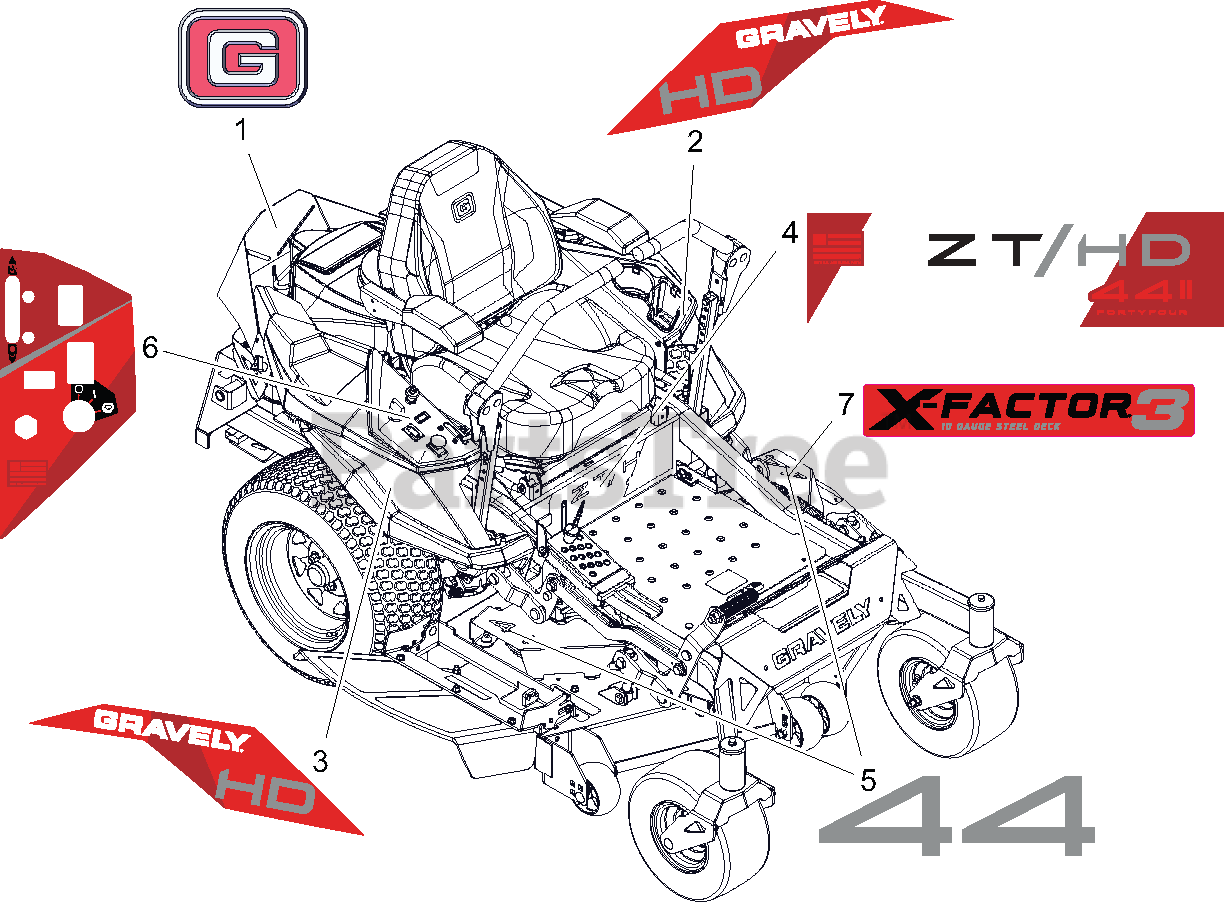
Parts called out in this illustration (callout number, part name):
1	DECAL, GRAVELY BRAND
2	DECAL, FENDER LH - HD
3	DECAL, FENDER RH - HD
4	DECAL, ZT/HD - 44
5	DECAL, DECK - 44
6	DECAL, CONTROL PANEL
7	DECAL, X-FACTOR 3
